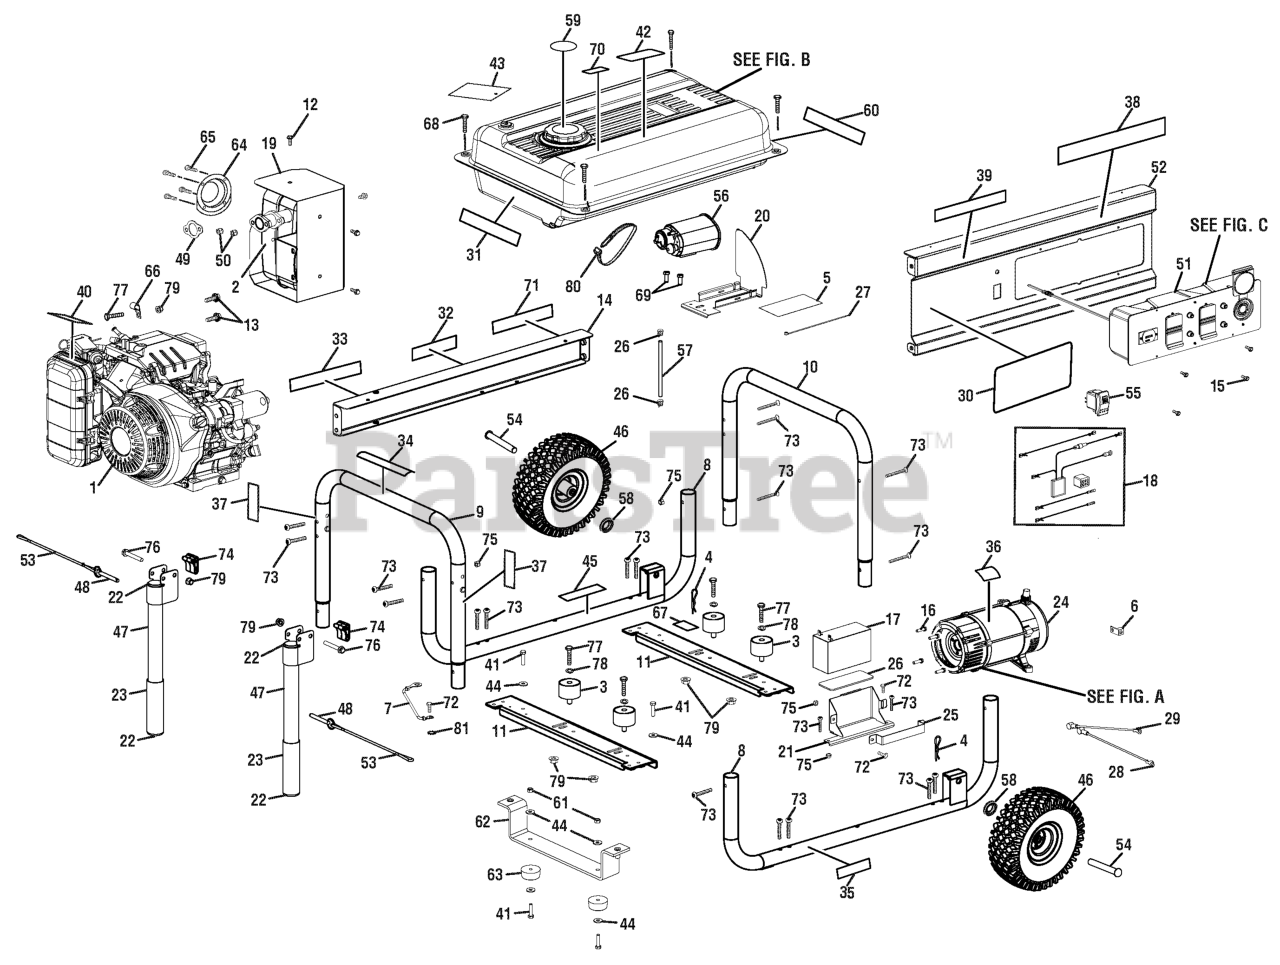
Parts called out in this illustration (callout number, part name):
1	Engine (Honda)(Parts available at your local Honda dealer)
2	MUFFLER
3	ISOLATOR
4	HITCH PIN
5	RUBBER SHEET
6	GROUND LUG
7	GROUND WIRE ASSEMBLY
8	LOWER FRAME ASSEMBLY
9	TUBE ASSEMBLY (LEFT)
10	TUBE ASSEMBLY (RIGHT)
11	CROSS BRACE
12	BOLT (M6 X 9 MM)
13	BOLT (5/16-24 X 5/8 IN.)
14	BACK PANEL
15	SCREW (6-20 X 3/8 IN.)
16	BOLT (3/8-16 X 1.25 IN.)
17	BATTERY
18	WIRE HARNESS
19	HEAT SHIELD
20	BRACKET (CARBON CANISTER)
21	BATTERY BOX
22	END CAP
23	HANDLE GRIP
24	GENERATOR HEAD ASSEMBLY
25	BATTERY BOX
26	FUEL LINE CLAMP (1/2 IN.)
27	TIE WRAP
28	BATTERY CABLE (RED)
29	BATTERY CABLE (BLACK)
30	LOGO LABEL
31	STARTING INSTRUCTIONS LABEL
32	HOT SURFACE LABEL
33	DANGER LABEL
34	FIRE DANGER LABEL
35	ENGINE LUBRICANT LABEL
36	DATA PLATE LABEL
37	LOCKING PIN LABEL
38	HONDA LABEL
39	ELECTRIC START LABEL
40	CHOKE LABEL
41	BOLT (M6 X 1 IN., HEX HD.)
42	CPSC LABEL
43	DANGER HANG TAG
44	WASHER (ID6.4 X OD17 X 1.6T)
45	COMBUSTION WARNING LABEL
46	WHEEL ASSEMBLY
47	HANDLE ASSEMBLY
48	RELEASE PIN (5/16 X 2 IN.)
49	EXHAUST GASKET
50	NUT( M8)
51	PANEL ASSEMBLY
52	FRONT PANEL
53	LANYARD (3/16 IN.)
55	ENGINE SWITCH
56	CANISTER
57	PURGE HOSE
58	WASHER (1/2 IN.)
59	FUEL STABILIZER LABEL
60	GROUND WARNING LABEL
61	NUT (M6)
62	FOOT BRACKET
63	WEAR PAD
64	SPARK ARRESTOR
65	SCREW (8-32 X 3/8 IN.)
66	J-CLAMP
67	GROUND LABEL
68	SCREW (1/4-14 X 1.25 IN.)
69	SCREW (#10-16 X 3/4 IN.)
70	E85 LABEL
71	FIRE DISTANCE LABEL
72	SCREW (M6 X 16 MM, HEX HD.)
73	SCREW (M6 X 50 MM, T30, PANHD)
74	HANDLE BRACKET SPACER
75	NUT (M6)
76	BOLT (M8 X 55 MM, HEX HD.)
77	BOLT (M8 X 35 MM, HEX HD.)
78	WASHER (M8)
79	NUT (M8)
80	CABLE TIE
81	STAR WASHER (M8)
